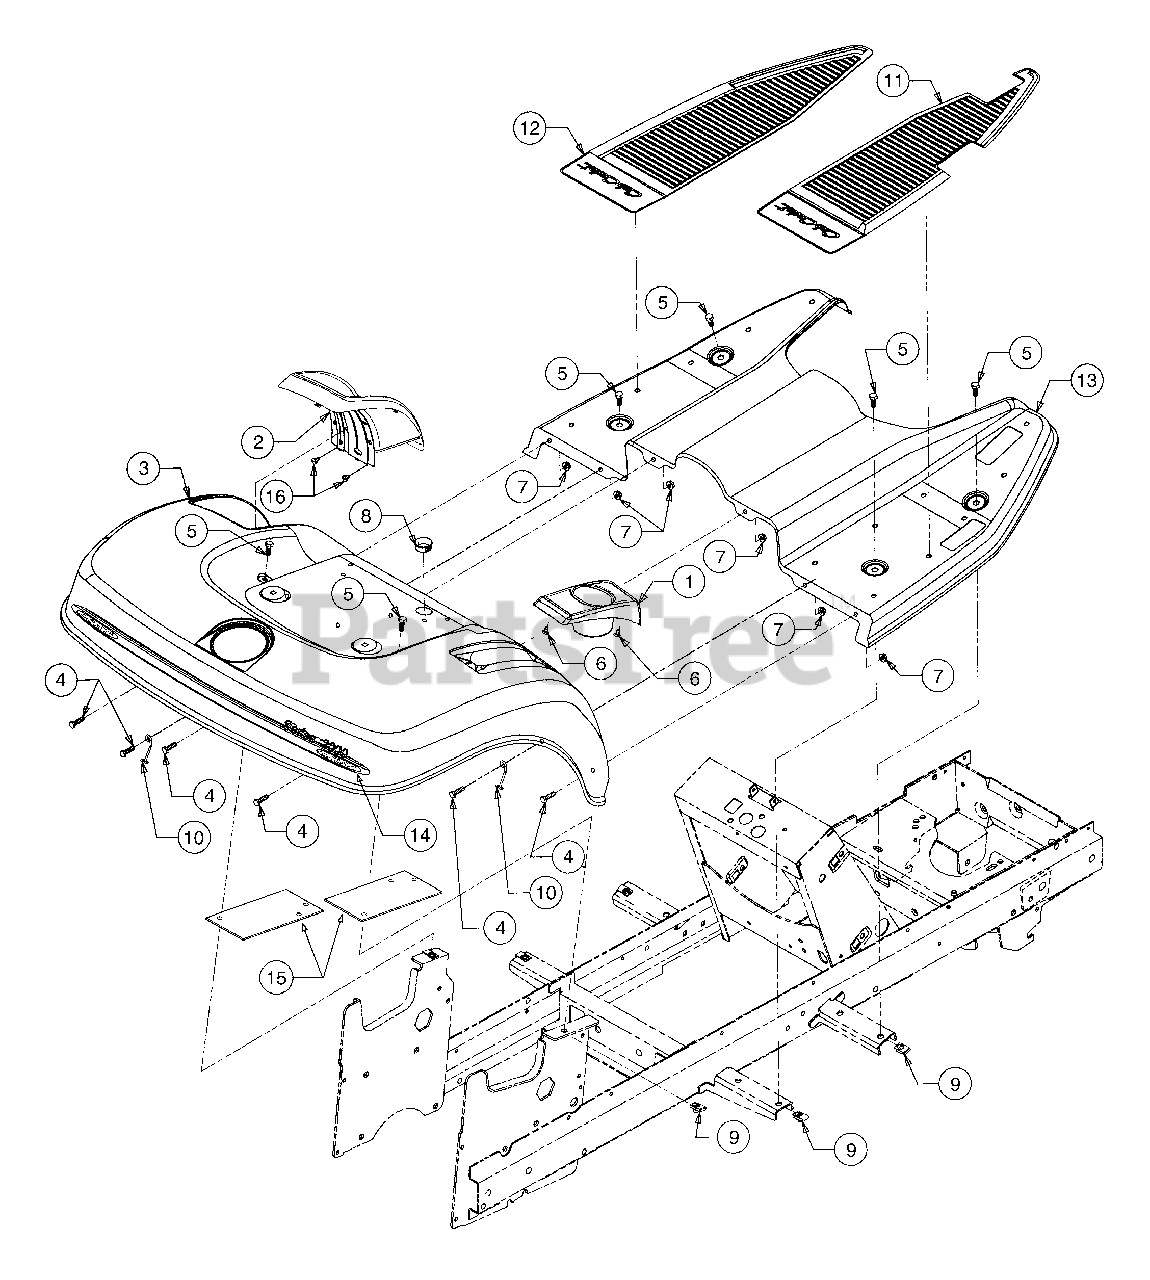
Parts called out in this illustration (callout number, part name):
1	Cup Holder
2	Cover, Implement Lift
4	Screw, Hex Cap, 1/4-20 x .62 GR5
5	Screw, Hex Wash Hd Tapp 5/16-18 x .750
6	Screw, Hex Tapp, #10 x .38 Lg
7	Nut, Hex Flange Lock, 1/4-20
8	Bushing, Snap, 7/8 ID
9	U-Nut, 5/16-18
10	Retainer, Hook
11	Pad, RH Foot
12	Pad, LH Foot
13	Running Board w/Graphic
14	Graphic, Rear Fender
15	Bracket, Fender Reinforcement
16	Screw, Hex Tapp, #10-16 x .5 Lg.
